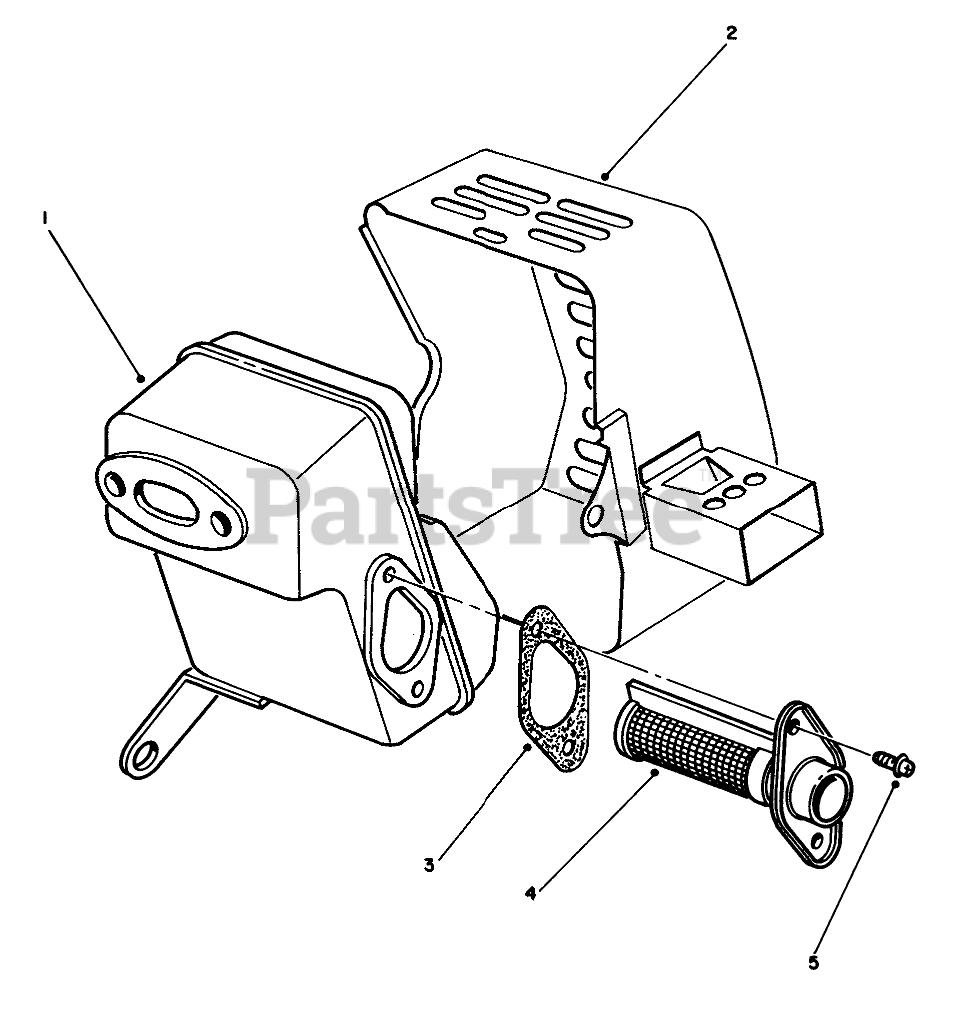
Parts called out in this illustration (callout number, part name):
1	Muffler
2	Cover-Muffler
3	Gasket
4	Spark Arrestor
5	Screw & Washer
